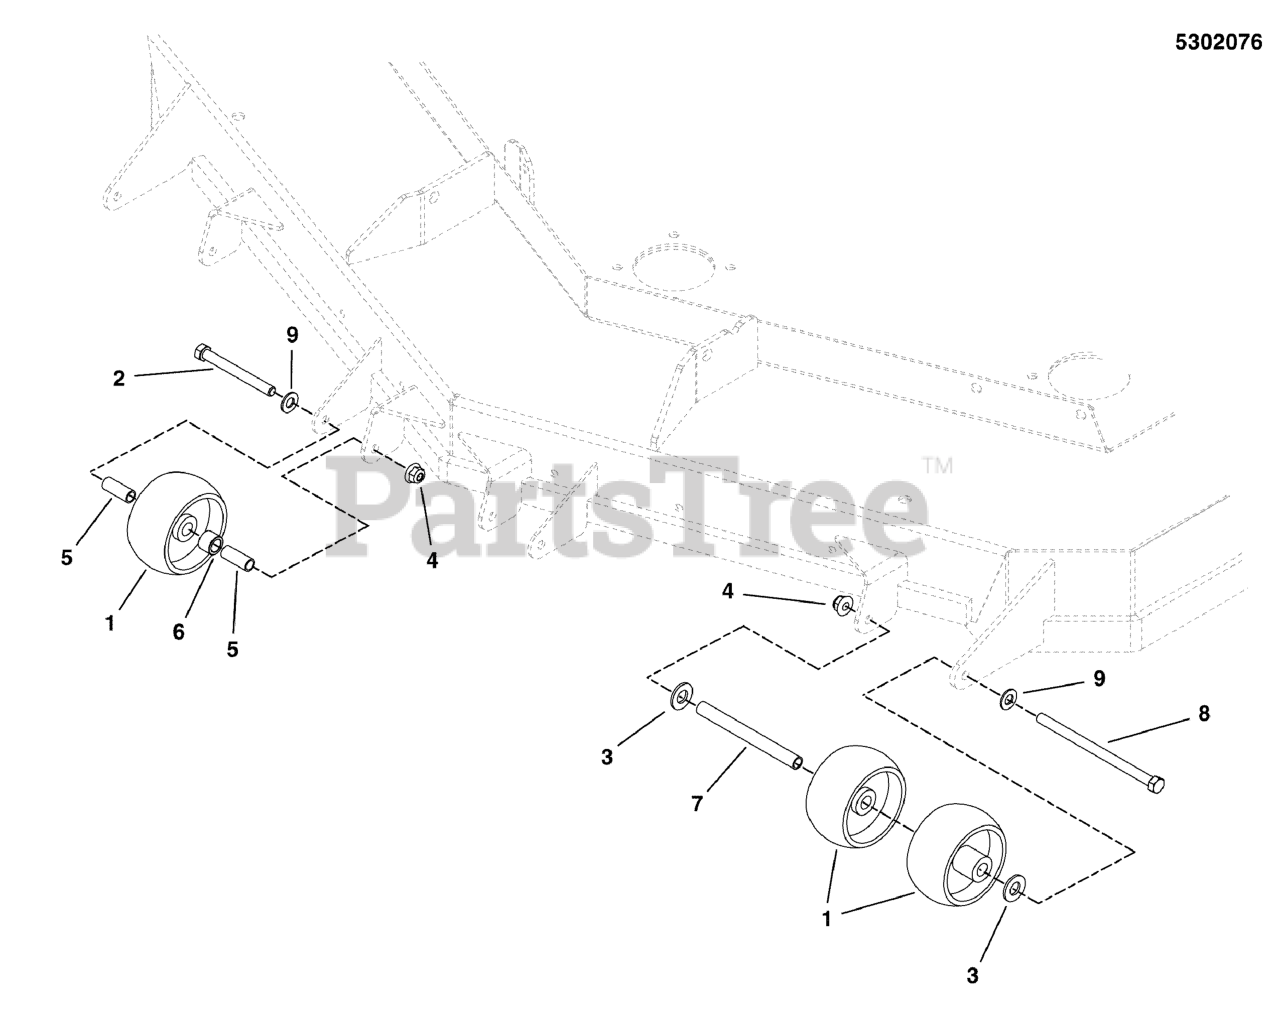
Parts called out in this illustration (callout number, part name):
1	WHEEL- 2.00 WIDE 3.88 DIA 0.531ID POLY
2	BOLT, 3/8-16 X 1-3/4" GD5 CZ
3	WASHER, 1/2 SAE
4	NUT, 3/8-16 HEX NYLOCK FLANGE
5	SPACER, .38 X .50 X 1.25, CZ
6	SPACER, .51 X .75 X .56
7	SPACER, .38 X .50 X 5.06
8	BOLT, 3/8-16 X 6" GD5 CZ
9	WASHER, 3/8 SAE
